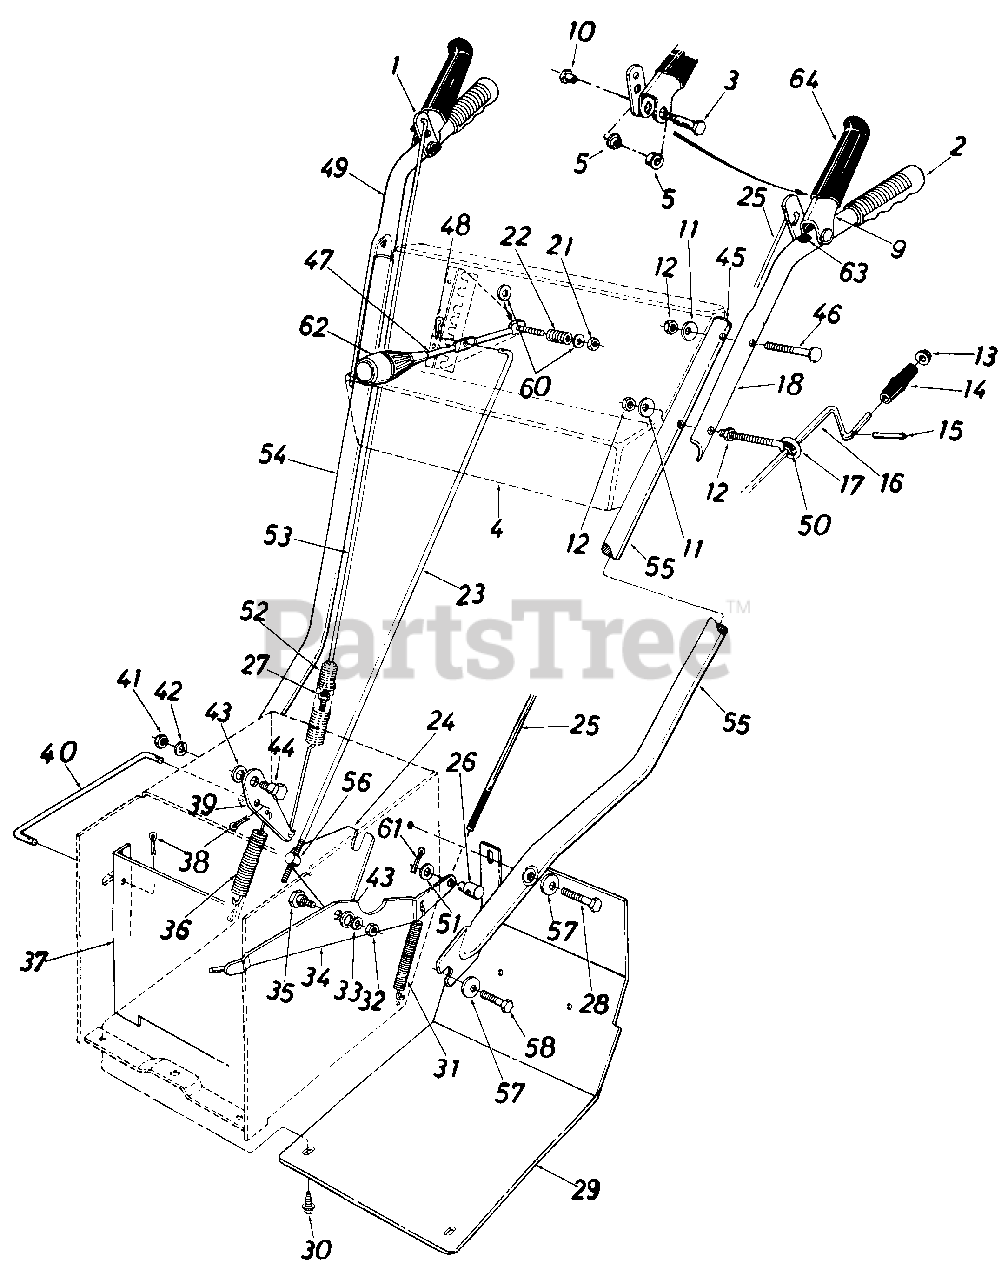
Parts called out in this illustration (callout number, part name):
1	Clutch Grip Ass'y.-R.H.
3	Shoulder Bolt .374 Dia. x 1 .375" Lg.
4	Handle Panel Ass'y.
5	Hex Flange Plastic Bearing .380" I.D.
9	Clutch Grip Ass'y.-L.H.
10	Shoulder Nut 1/4-20 Thd.
11	Bell-Wash. .34" I.D. x .88" O.D.
12	Hex Nut 5/16-18 Thd.*
13	Push Nut 3/8" Rod
14	Knob 3/8" Rod
15	Roll Pin .12 Dia. X .63" Lg.
16	Chute Crank Ass'y. 39" Lg.
17	Eye Bolt 5/16-18 x 5.0'/ Lg.
18	Upper Handle-L.H.
21	Hex Ins. Jam L-Nut 5/16-18 Thd.
22	Compression Spring .50" O.D. x .88" Lg.
23	Shifting Rod 5/16" x 32.50" Lg.
24	Shifting Linkage Bracket
25	Lockout Rod .214" Dia. x 36.0" Lg.
26	Adjustment Ferrule 1/4-20
27	Hex Ins. L-Nut 1/4-20 Thd.
28	Hex Bolt 3/8-16 x 2.00" Lg.*
29	Frame Cover
30	Hex Wash. Self-Tap Scr. 1/4 -20 x .50" Lg .
31	Extension Spring .38" O.D. x 3.25" Lg.
32	Hex Jam Nut 3/8-16 Thd.*
33	L-Wash. 3/8" I.D.*
34	Auger Clutch Bracket Ass'y.
35	Shld. Bolt .625" Dia. x .170
36	Extension Spring .75" O.D. x 4.31 " Lg.
37	Drive Pulley Support Brkt. Ass'y.
38	Cotter Pin 3/32" Dia. x .75" Lg.*
39	Drive Clutch Bracket
40	Drive Clutch Rod
41	Hex Jam Nut 3/8-16 Thd.*
42	L-Wash. 3/8" I.D.*
43	Bell-Wash. .40" I.D. x 1.13" O.D.
44	Shld. Bolt .625" Dia. x .170
45	Plastic Plug
46	Carriage Bolt 5/16-18 x 2.0" Lg.
47	Shift Handle
48	Int. Cotter Pin 5/16" Dia.
51	Fl-Wash. .344" I.D. x .62" O.D.
52	Extension Spring .75" O.D. x 5.00" Lg.
53	Lockout Rod .214" Dia. x 32" Lg.
54	Lower Handle-R.H.
55	Lower Handle-L.H.
56	Adjustment Ferrule
57	Bell-Wash. .40" I.D. x .88" O.D.
58	Hex Wash. Self-Tap Scr. 3/8-16 x .75" Lg.
60	Fl-Wash. .344" I.D. x .62" O.D.
61	Cotter Pin 3/32" Dia.
63	Push Cap
64	Black Vinyl Grip
